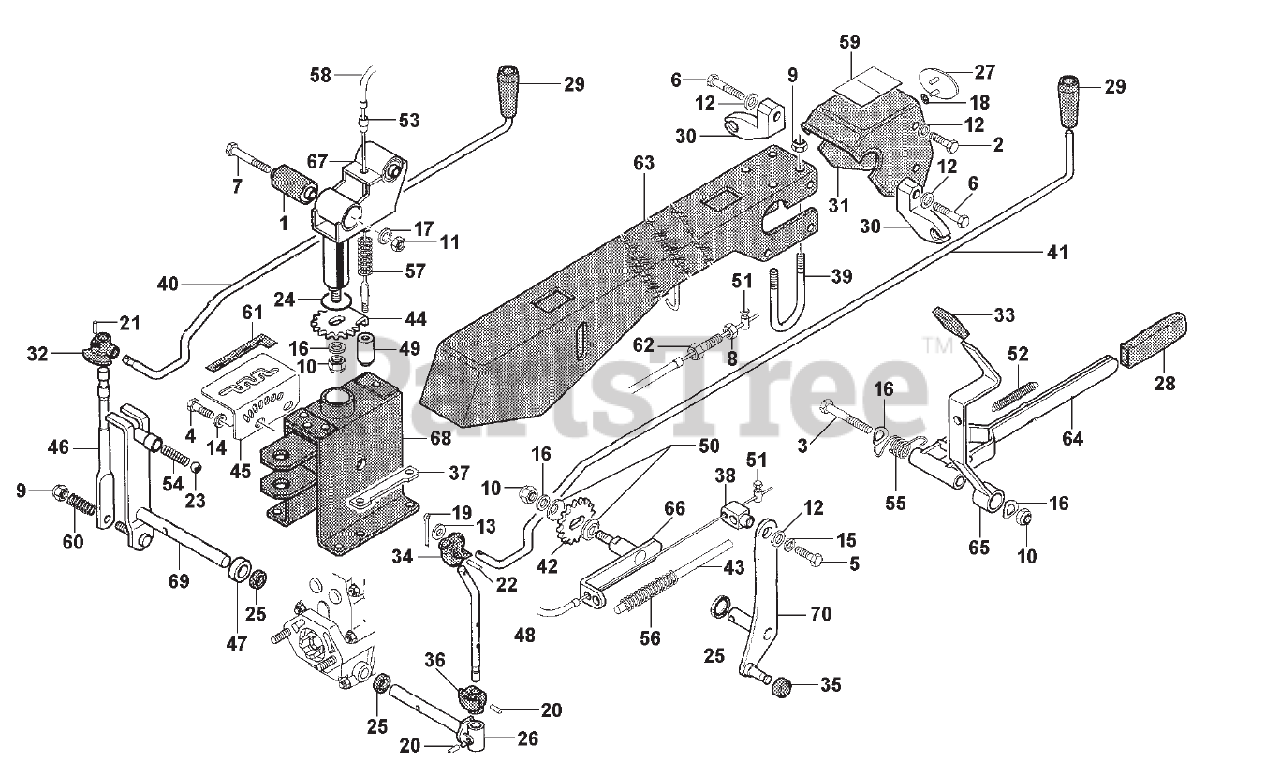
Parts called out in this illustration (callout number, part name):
1	SILENTBLOCK
2	SCREW,M8X16
3	SCREW,M10X90
4	SCREW,M8X14
5	SCREW,M8X12
6	SCREW,M8X35
7	SCREW,M12X95
9	NUT,SELF LOCKING, M8
10	NUT,SELF LOCKING, M10
11	NUT,SELF LOCKING, M12
12	WASHER,FLAT,M8.4
14	WASHER,M8.4
15	WASHER,LOCK, M8.4
16	WASHER,LOCK, M10.5
17	WASHER,LOCK, M13
18	WASHER,LOCK FOR PINS
20	LOCKINGPIN, M4X20 SPIRAL
21	PIN,LOCKING, M3X22 SPIRAL
22	LOCKINGPIN, M4X24 SPIRAL
23	BALL 15/32 RIV RB-11.906
24	O-RING,M28.17X3.53
25	OILSEAL, M14X22X4
30	SUPPORTCONTROL ROD CUT
31	STEERINGCOLUMN INTERM. PANEL
32	GEARBOXARTICULATION
33	KNOBREDUCTION UNIT LEVER
34	PTOARTICULATION
35	PTOLOCKOUT RING
36	PTOSTOP RING
37	REVERSESPEED LEVER DOG
38	REVERSEBLOCK
39	HANDLEBARU-BOLT
40	GEARBOXCONTROL ROD
41	PTOCONTROL ROD
42	REVERSEGEAR
44	BENDEDREVERSER GEAR
45	GEARQUADRAINT
48	PTOCONTROL LEVER
50	PROTECTIONEND D 32
51	CLAMP,CABLE
55	HANDLEBARRELEASE SPRING
56	REVERSERSPRING
57	PUSHROD SPRING
58	STEERINGCOLUMN CABLE
59	STEERINGCOLUMN STICKER
62	ADJUSTINGSCREW
63	STEERINGCOLUMN
64	HANDLEBARRELEASE LEVER
65	STEERINGCOLUMN LOCKING LEVER
66	REVERSERPOSTION LEVER
67	STEERINGCOLUMN COUPLING
68	STEERINGCOLUMN SUPPORT
69	SPEEDSELECTOR LEVER
70	REVERSERLEVER
